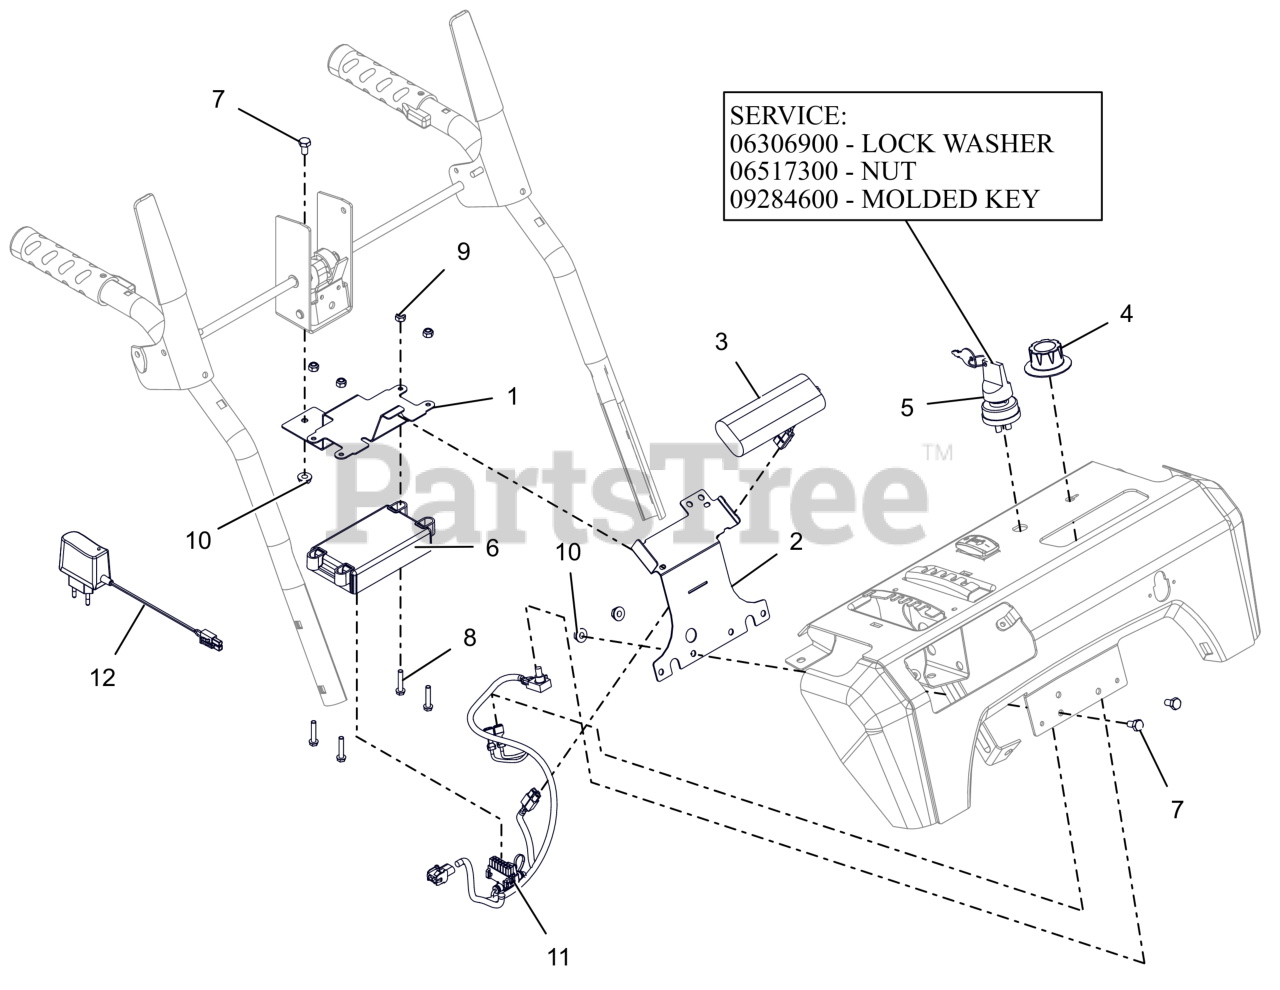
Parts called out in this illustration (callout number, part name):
1	BRACKET, ENGINE EFI-LCT LOWER
2	BRACKET, ENGINE EFI-LCT UPPER
3	BATTERY, SNOW EFI - 7.2V
4	KNOB, CONTROL - 2.063 ID
5	IGNITION SWITCH ASM - 2 POS
6	ECU, AX369 EFI
7	BLT,HEX .25-20X.50 G5 ZCC
8	BLT, HWH #10-24X1.00 ZCC
9	NUT-LK-NYL #10-24 G2 ZCC
10	NUT-LK-TOP-FLG .250-20 GF ZCC
11	HARNESS,WIRE - EFI ECU
12	CHARGER, BATTERY-EFI 7.2V (EU)
